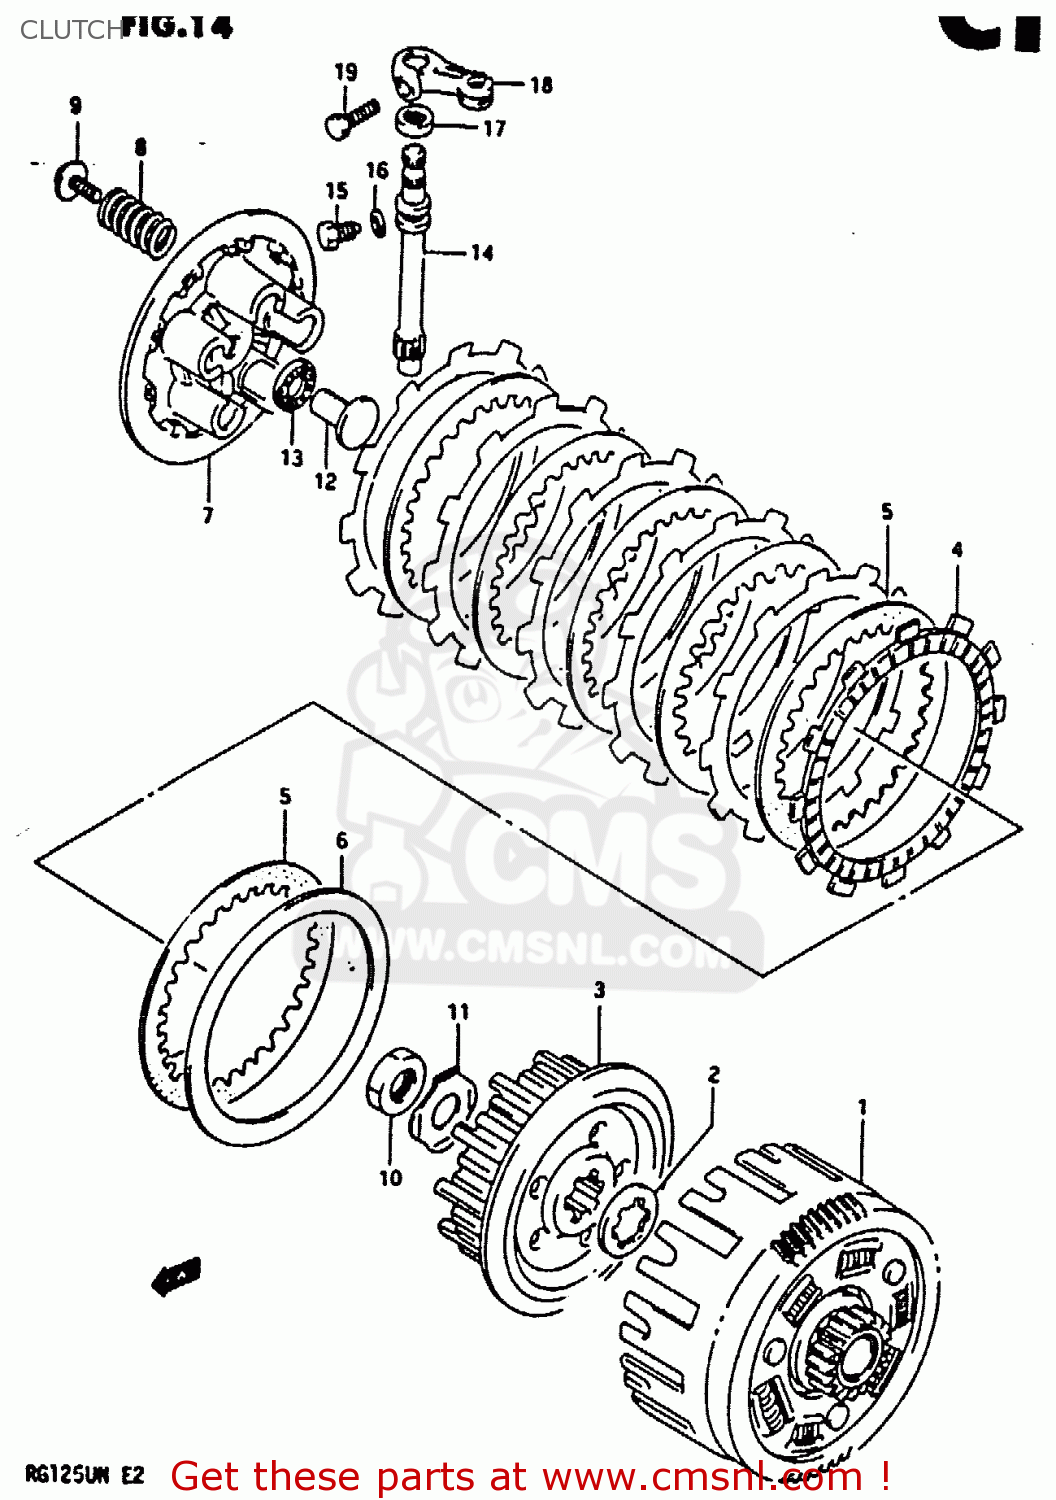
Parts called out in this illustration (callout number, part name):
1	GEAR ASSY,PRI DRIVEN
2	** SUPERSEEDED
3	HUB,CLUTCH SLEEVE
4	PLATE,CLUTCH DRIVE(T:3.0) (NAS)
5	PLATE,CLUTCH DRIVEN(T:2.0) (NAS)
6	SEAT,WAVE WASHER
7	DISC,CLUTCH PRESSURE
8	SPRING
9	BOLT 5X16
10	NUT
11	WASHER
12	RACK,CLUTCH RELEASE
13	BEARING(10X22X2.8)
14	PINION,CLUTCH RELEASE
15	BOLT(6X12)
16	WASHER
17	SEAL,OIL(10X17X5)
18	ARM,CLUTCH RELEASE
19	BOLT
